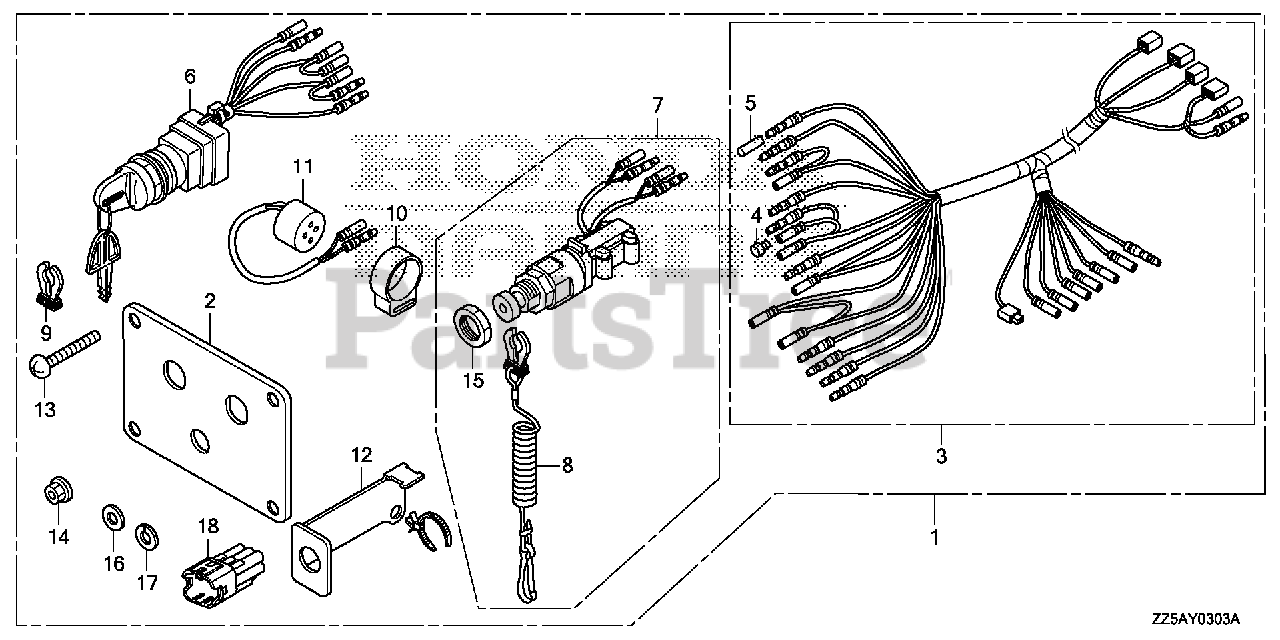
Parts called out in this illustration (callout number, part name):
1	PANEL KIT, SWITCH (TWIN)
2	PANEL, CONTROL (TWIN)
3	HARNESS ASSY., SWITCH PANEL
4	PLUG, CONNECTOR (INNER)
5	PLUG, CONNECTOR (OUTER)
6	SWITCH ASSY., COMBINATION
7	SWITCH ASSY., EMERGENCY STOP (TWIN)
8	WIRE, EMERGENCY
9	CLIP, EMERGENCY LOCK
10	SUSPENSION, AUDIBLE PILOT
11	BUZZER, WARNING
12	BRACKET
13	SCREW, PAN (5X40)
14	NUT, FLANGE (5MM)
15	NUT
16	WASHER, PLAIN (5MM)
17	WASHER, SPRING (5MM)
18	DUMMY, WATERPROOF CONNECTOR (GREEN)
